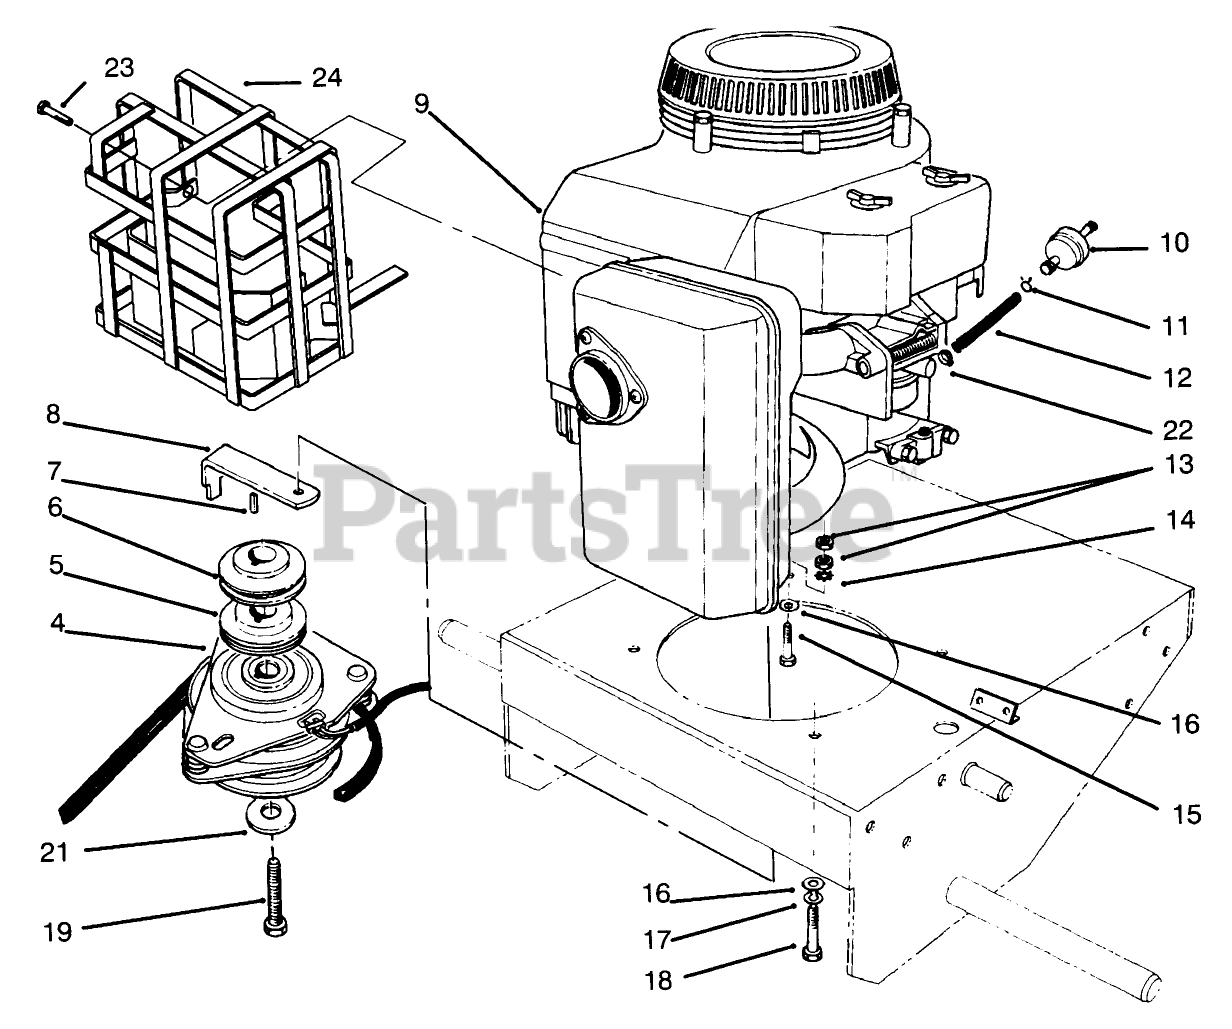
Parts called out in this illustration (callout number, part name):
4	CLUTCH/BRAKE
5	SHEAVE-LOWER HALF
6	SHEAVE-UPPER HALF
8	Retainer-Clutch
10	FILTER-FUEL
11	CLAMP-HOSE
12	HOSE-FUEL
13	NUT-JAM
14	WASHER-LOCK
15	SCREW (ENGINE, GROUND)
16	WASHER-PLAIN
17	WASHER-LOCK
18	SCREW-HH
19	SCREW-CLUTCH
21	WASHER
22	CLAMP-WORM
23	Screw-Hex. Hd. (Engine)
24	ASM - MUFFLER GUARD
